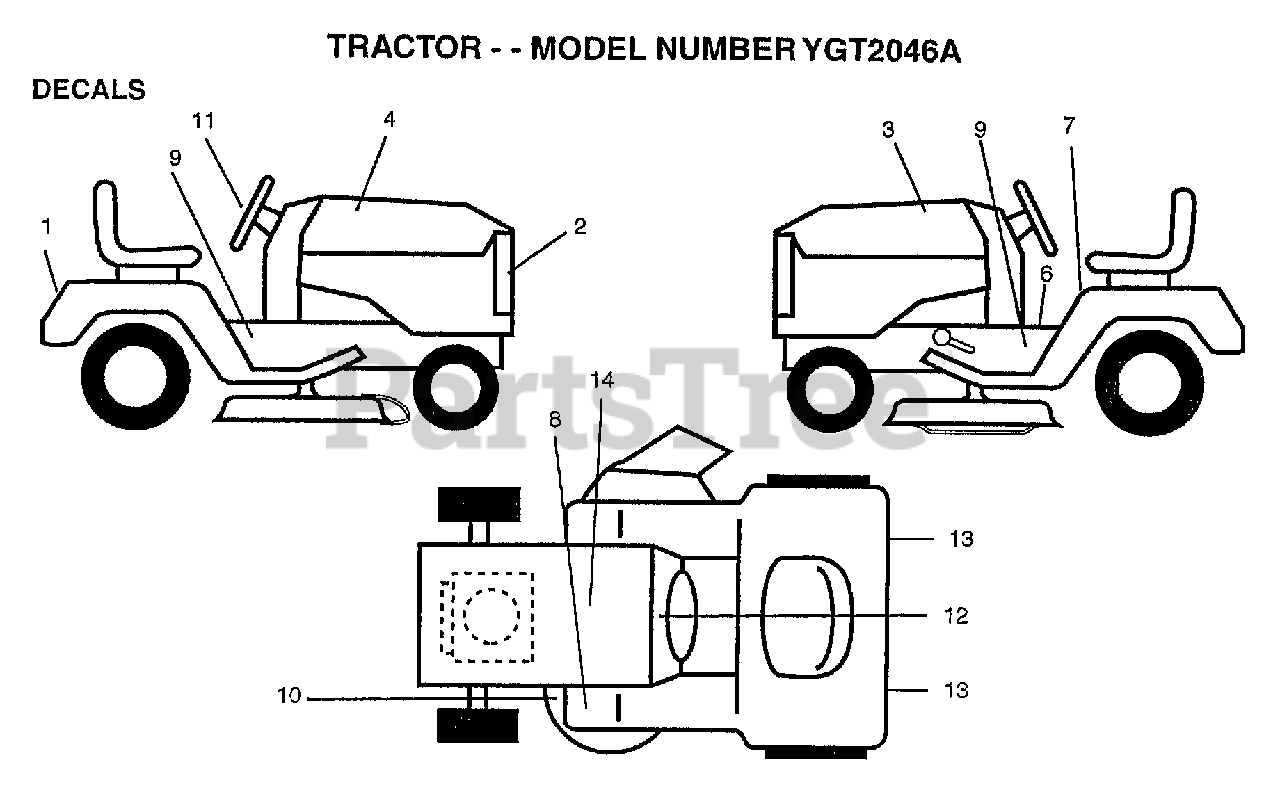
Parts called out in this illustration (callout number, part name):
1	HARNESS-IGNITION
2	DECAL GRILLE
3	"DECAL HOOD,LH"
4	"DECAL HOOD,RH"
6	DECAL BRAK PARK
7	"DECAL DANGER,FEND"
9	"DECAL CHASSIS,46"""
10	"DECAL.V.BELT.44"""
11	DECAL INS STRG WH
12	"DECAL-OPER,GEAR D"
13	REFLECTOR-TAIL YT
14	DECAL.BATRY.3-3908
